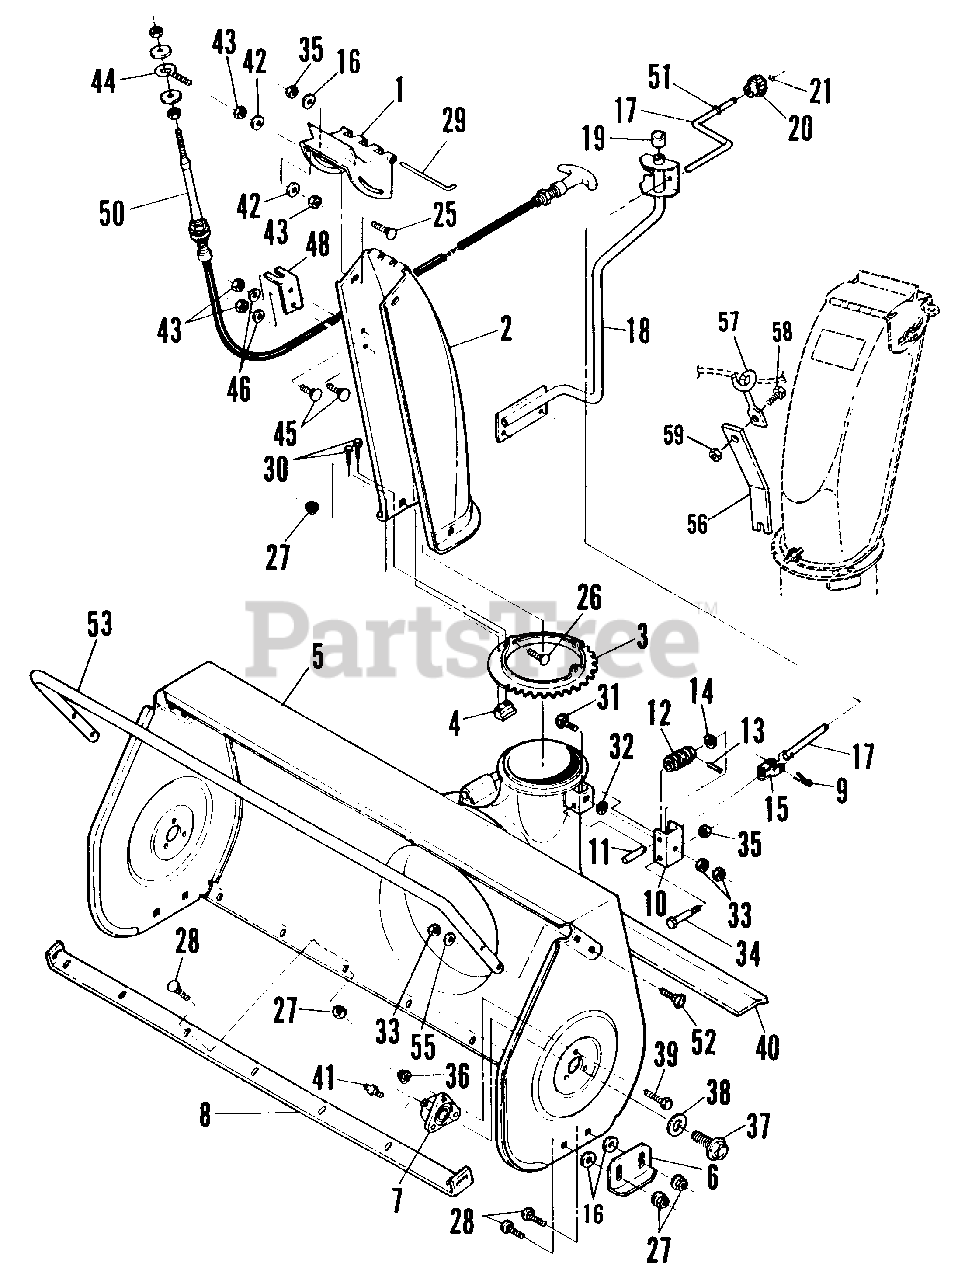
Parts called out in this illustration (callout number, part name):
1	DEFLECTOR, Discharge
2	CHUTE & DECAL ASS'Y.
3	RING, Chute
4	RETAINER, Chute Ring
5	HOUSING & DECAL ASS'Y.
6	SHOE, Skid
7	BEARING, Auger Shaft
8	BLADE, Scraper
9	PIN, 1/8 x 1 1/4" Cotter
10	BRACKET, Worm
11	SHAFT, Worm
12	WORM
13	ROLL-PIN, 1/8 x 3/4"
14	WASHER, Spring Steel
15	CONNECTOR
16	WASHER, 5/16" Flat
17	CRANK, Chute
18	BRACE, Chute Crank
19	CAP, Crank Brace
20	KNOB, Chute Crank
21	NUT, 5/16 - 18 Hex Lock
25	SCREW, 5/16 - 24 x 3/4" Hex Head Cap
26	BOLT, 5/16 - 18 x 5/8" Carriage
27	NUT, 5/16 - 18 Hex Flange Lock
28	BOLT, 5/16 - 18 x 3/4" Carriage
29	PIN, Hinge
30	SCREW, #10 - 24 x 5/8" Self-Tapping
31	BOLT, 5/16 - 18 x 1" Carriage
32	RETAINER, Bolt
33	NUT, 5/16 - 18 Hex
34	SCREW, 5/16 - 24 x 2 1/2" Hex Head Cap
35	NUT, 5/16 - 24 Hex Lock
36	NUT, 1/4 - 20 Hex Flange Lock
37	SCREW, 3/8 - 16 x 3/4" Self Tap
38	WASHER, 3/8" Flat
39	BOLT, 1/4 - 20 x 3/4" Hex Flange Lock
40	BAR, Stiffener
41	FITTING, Lube (Press fit for .187 hole-no ball)
42	WASHER, 1/4" Flat
43	NUT, 1/4 - 20 Hex
44	BOLT, 1/4 - 20 Eye
45	BOLT, 1/4 - 20 x 1/2" Carriage
46	WASHER, 1/4" Internal Tooth Lock
48	MOUNT, Cable
50	CABLE, Control
51	BUSHING
52	BOLT, 5/16 - 18 x 1 1/2" Curved Head
53	DRIFT CUTTER
55	WASHER, 5/16" Split Lock
56	BRACKET, Cable Support
57	BRACKET, Pull Rope
58	SCREW, 1/4-20 x 5/8" Hex Head Cap
59	NUT, 1/4-20 Hex Center Lock
